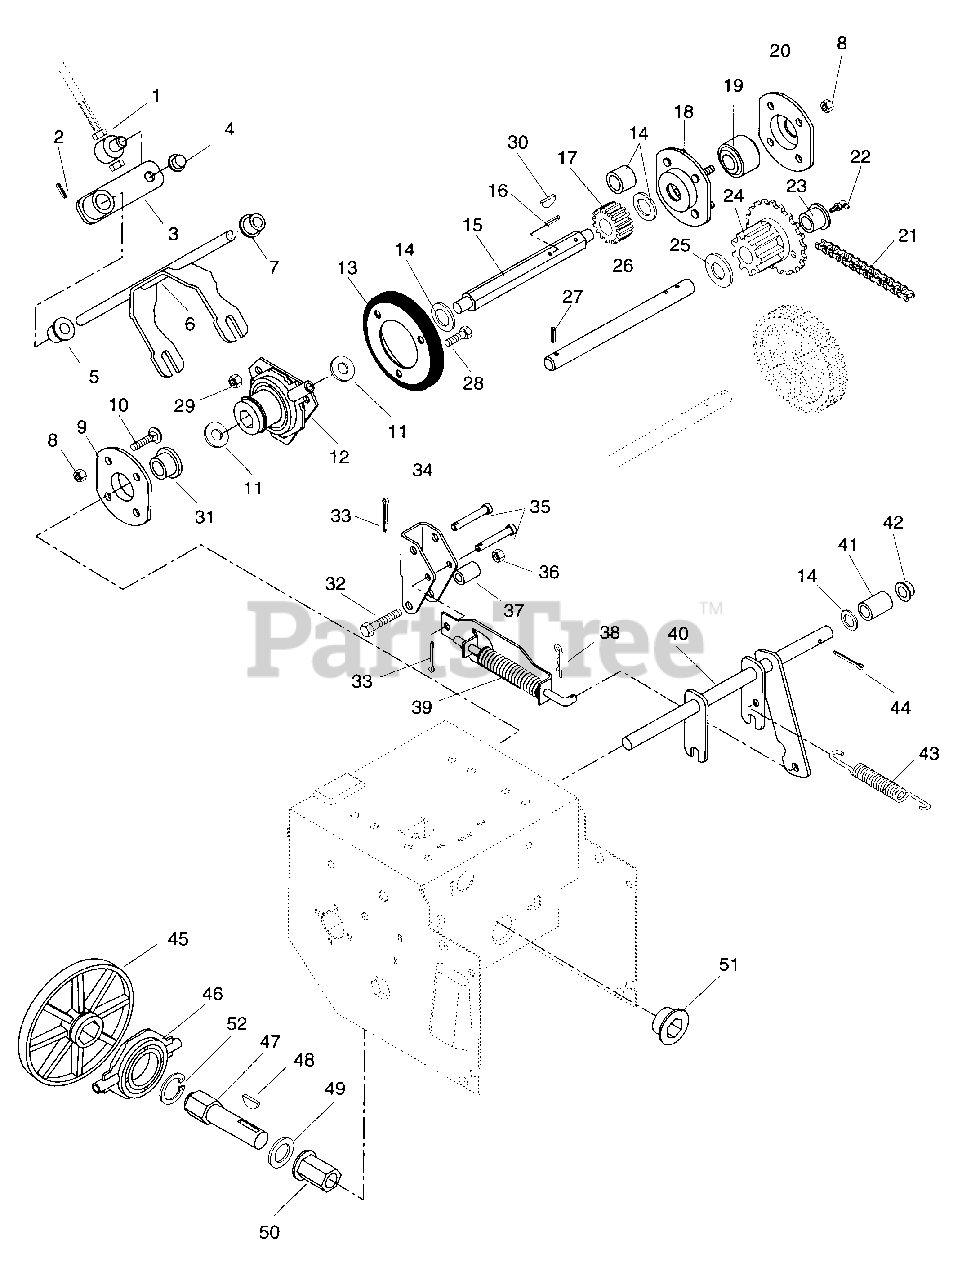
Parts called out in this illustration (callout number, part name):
2	PIN-ROLL .156X.88
3	ARM-SPEED CHANGE
4	CAP, 3/8 ROD YWZC
5	BSHG-FLG.500X.625X.312X.750NY
6	FORK-SPEED
7	BSHG-FLG .325X.444X.440X.560
8	NUT-LK DUAL FACE 10-24 PL
9	BUSHING FLANGE
10	BLT-RDHDSQNK 10-24X.38 PL
11	WSHR-FL-STL .505X1.000X.062
12	SHIFT CARRIER
13	FRICTION DISC
14	WSHR-FL-STL .531X1.062X.095 PL
14	SPACER .513X.748X.620
15	HEX SHAFT
16	PIN-ROLL .125X.88
17	PINION
17	9 TOOTH SPROCKET
18	BEARING FLANGE
19	BRG-BALL .500X1.38X.437
20	BEARING FLANGE
21	CHAIN-ROLLER #41X26 PITCHES
22	HYDRAULIC DRIVE FITTING
23	BSHG-FLG .625X.750X.500X.875BR
24	SPROCKET ASSY
25	WSHR-FL-STL .630X1.005X.062 PL
26	SHAFT-PINION
27	PIN-ROLL .125X1.00
28	BLT-HEX .25-20X.50 PL GR2
29	NUT-LK-CTR .250-20 PL
30	KEY-WDRF .125X.625X.250 SAE5
31	BSHG-FLG .500X.750X.625X.937
32	BLT-HEX .31-18X1.50 PL GR2
33	PIN COTR .09X.50 PL
34	BRACKET
35	PIN, CLEVIS .243/.248X1.50 YWZ
36	NUT-LK .312-18 GR A PL
37	SPACER -SPLIT .340X.490X1.02
38	PIN-HAIR INT .08X.18X1.18
39	TRACTION CLUTCH ASSY
40	CLUTCH FORK
41	SPACER .504X.748X.321
42	CAP, .50 ROD YWZC
43	SG-TENS .063X.44X1.56
44	PIN-COTR .12X1.0 PL
45	FRICTION PLATE
46	BEARING ASSEMBLY
47	HEX SHAFT
48	KEY-WDRF .188X.75X.313 SAE 9
49	WSHR, THRUST .625X1.125X.063
50	BSHG-FLG .625X.875X1.750X1.188
51	BSHG-FLG .875X1.25X.75X1.50HX
52	RG-RTNG-EXT 1.250X.050
